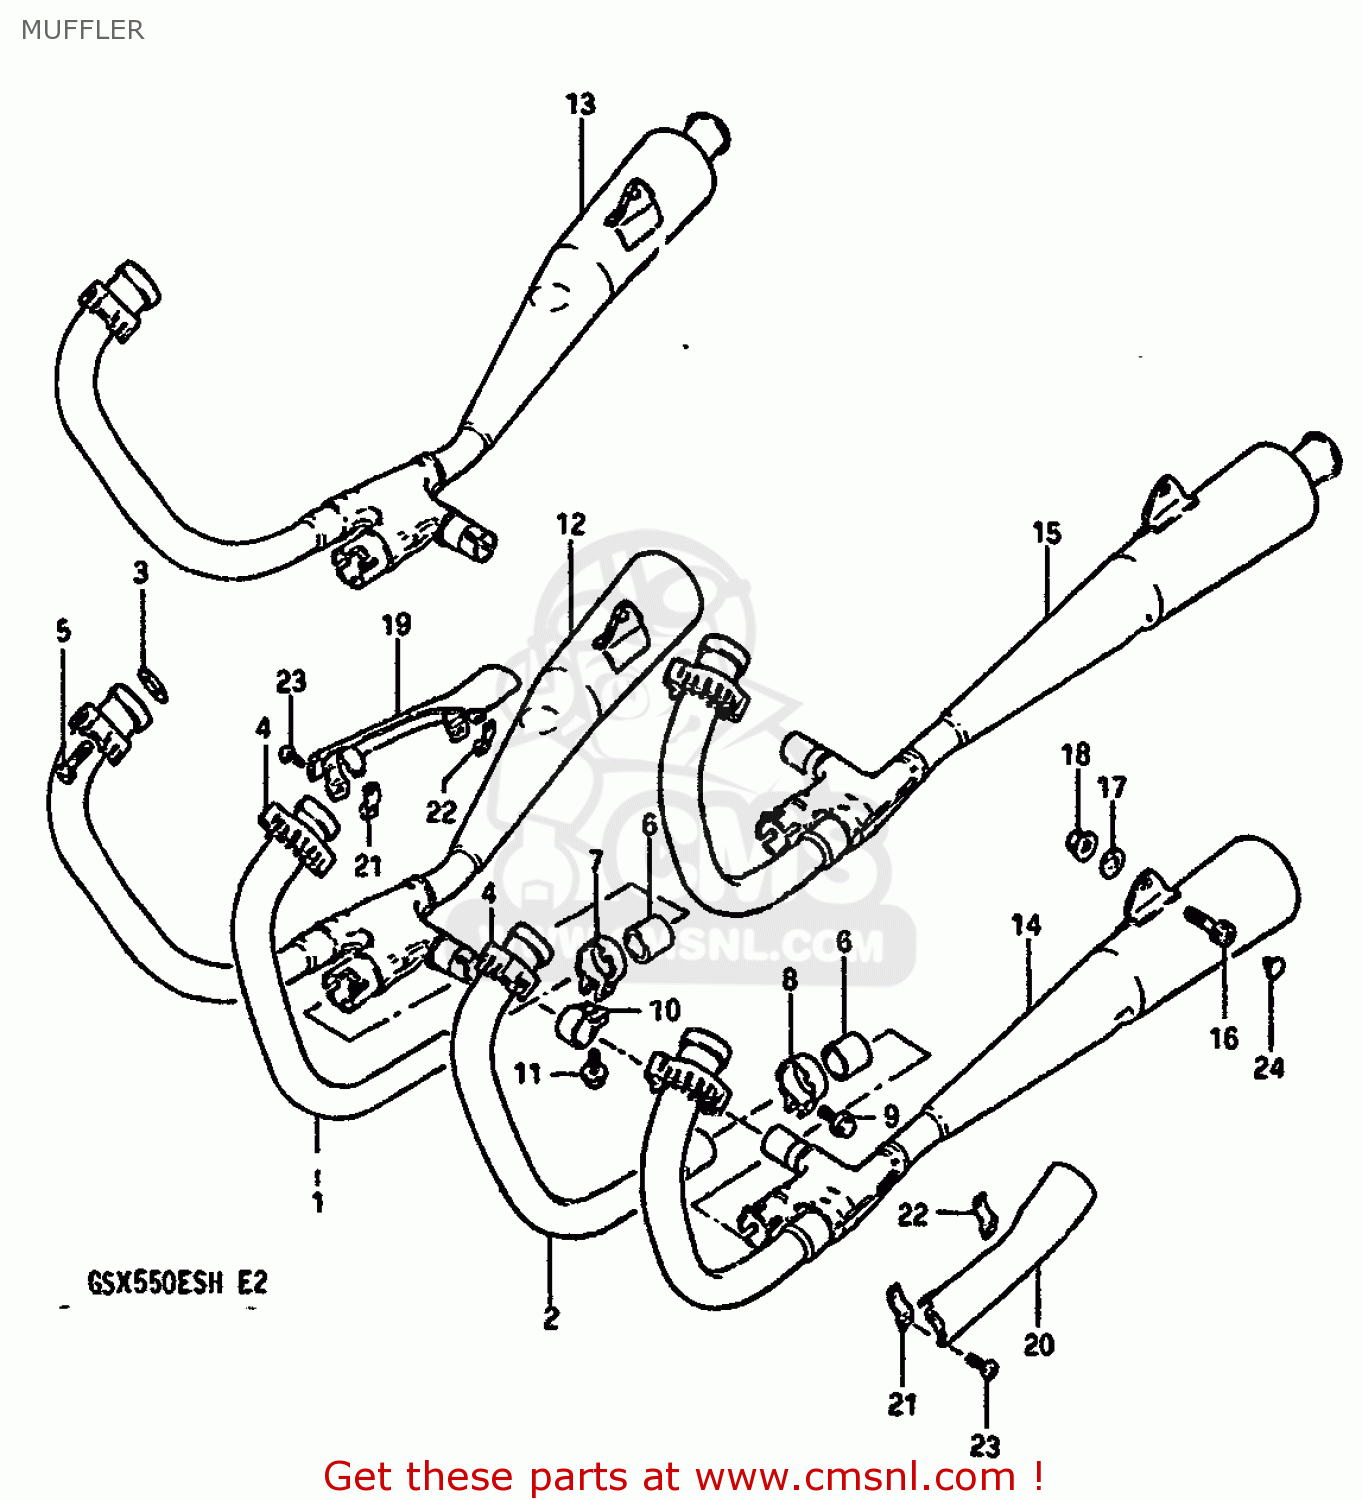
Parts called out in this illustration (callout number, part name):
1	PIPE,EXHAUST CENTER RH
2	PIPE,EXHAUST CENTER LH
3	GASKET,EXHAUST PIPE (NAS)
4	CLAMP,EXHAUST PIPE
5	BOLT
6	CONNECTOR,MUFFLER
7	CLAMP,MUFFLER CONNECTOR
8	CLAMP,MUFFLER CONNECTOR
9	BOLT
10	CLAMP,EXHAUST
11	BOLT
12	MUFFLER, RH
13	MUFFLER,RH
14	MUFFLER, LH
15	MUFFLER,LH
16	BOLT
17	WASHER(10.5X20X3.2)
18	NUT
19	COVER,MUFFLER,RIGHT
20	COVER,MUFFLER,LEFT
21	CLAMP,MUFFLER COVER
22	CLAMP,MUFFLER COVER
23	SCREW
24	CAP
